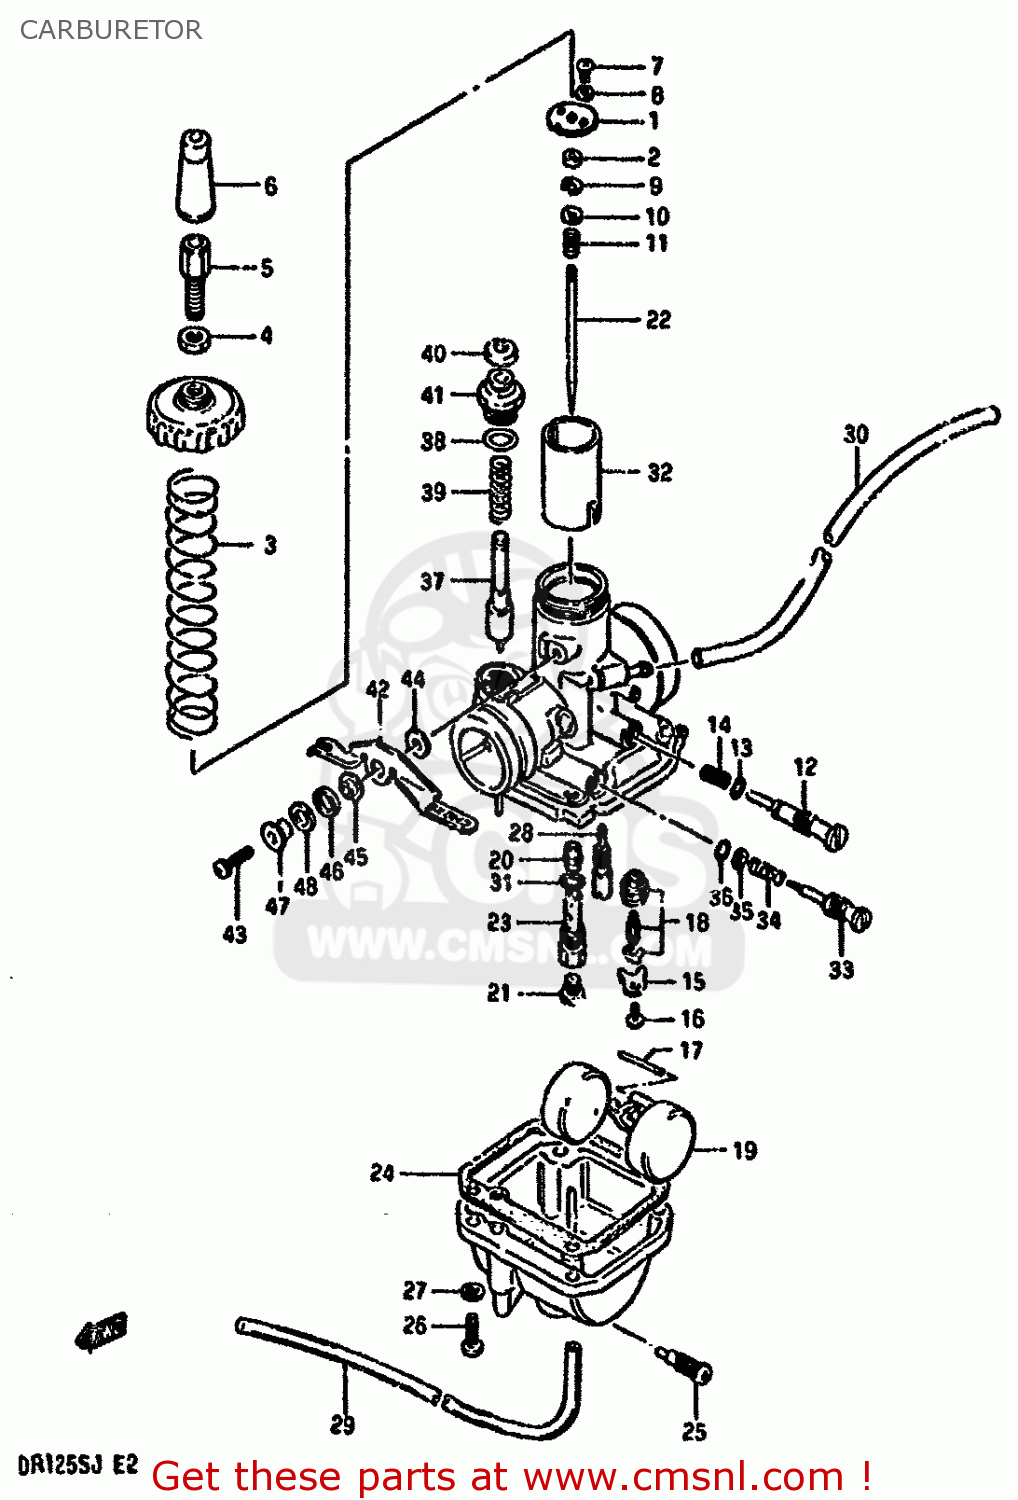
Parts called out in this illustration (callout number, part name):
1	PLATE
2	RING
3	SPRING
4	NUT
5	ADJUSTER,CABLE
6	CAP,RUBBER
7	SCREW
8	LOCK WASHER
9	CLIP
10	WASHER,JET NEEDLE
11	SPRING
12	SCREW,THROTTLE STOP
13	O RING
14	SPRING
15	PLATE,NEEDLE VALVE FITING
16	SCREW
17	PIN,FLOAT
18	VALVE ASSY,NEEDLE
19	FLOAT
20	JET,NEEDLE(N-8)
21	JET,MAIN
22	NEEDLE,JET
23	PIPE
24	GASKET (NAS)
25	PLUG,DRAIN
26	SCREW
27	WASHER,LOCK 4M
28	JET,PILOT(30)
29	HOSE
30	HOSE
31	O RING
32	VALVE,PISTON
33	SCREW,PILOT AIR
34	SPRING
35	GASKET
36	O RING,PILOT AIR SCREW
37	PLUNGER ASSY
38	O RING
39	SPRING
40	CAP,STARTER VALVE
41	HOLDER
42	LEVER
43	SCREW
44	PLATE
45	RING
46	WASHER
47	RING
48	WASHER,LOCK,8.
